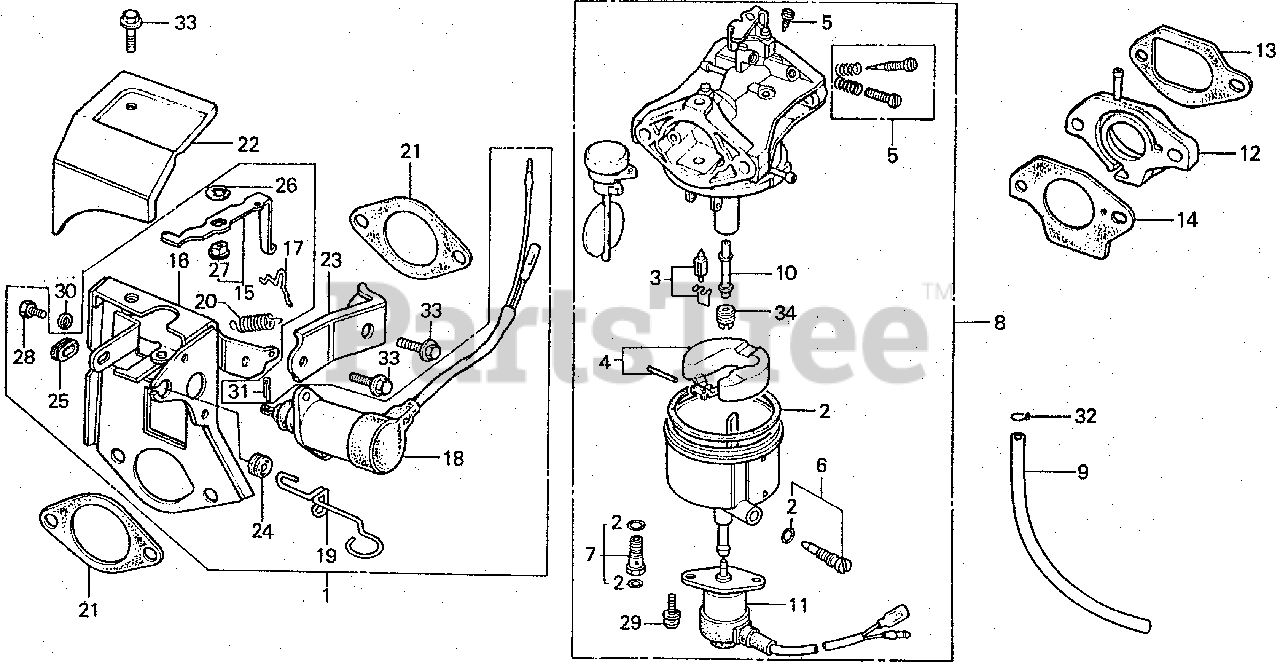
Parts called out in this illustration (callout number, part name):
1	STAY SET, SOLENOID
1	STAY SET, SOLENOID (NOT AVAILABLE)
2	GASKET SET
3	VALVE SET, FLOAT
4	FLOAT SET
5	SCREW SET A
6	SCREW SET, DRAIN
7	SCREW SET
7	SCREW SET B
8	CARBURETOR ASSY. (BB37B B) (NOT AVAILABLE)
8	CARBURETOR ASSY. (BB37A C/D) (NOT AVAILABLE)
8	CARBURETOR ASSY. (BB37B E) (NOT AVAILABLE)
9	TUBE, DRAIN
10	NOZZLE, MAIN
11	VALVE ASSY., SOLENOID
12	INSULATOR, CARBURETOR (NOT AVAILABLE)
13	GASKET, INSULATOR
14	GASKET, CARBURETOR
15	LEVER, SOLENOID CHOKE
16	STAY SET, SOLENOID
16	STAY, SOLENOID
17	ROD, CHOKE (NOT AVAILABLE)
17	ROD, CHOKE
18	CHOKE, SOLENOID (N/A: USE ALTERNATE P/N 06162-ZA0-315)
18	CHOKE, SOLENOID (NA USE ALT:06162-ZA0-315)
19	ROD, MANUAL CHOKE (NOT AVAILABLE)
20	SPRING, CHOKE RETURN
21	GASKET, AIR CLEANER
22	COVER, SOLENOID
23	BRACKET, CHOKE STAY
24	GROMMET, CHOKE ROD
25	GUIDE, CHOKE ROD
26	E-RING (4MM)
27	BUSH, CHOKE LEVER
28	BOLT, HEX. (5X8)
28	SCREW, PAN (5X8)
29	SCREW-WASHER (5X12)
30	WASHER, SPRING (5MM)
31	PIN, COTTER (1.6X25)
31	PIN, SPLIT (2.0)
32	CLIP, TUBE (C9)
33	BOLT, FLANGE (6X12)
34	JET, MAIN (#98)
34	JET, MAIN (#100)
34	JET, MAIN (#102)
34	JET, MAIN (#82)
34	JET, MAIN (#85)
34	JET, MAIN (#88)
34	JET, MAIN (#92)
NI	CHAMBER SET, FLOAT
